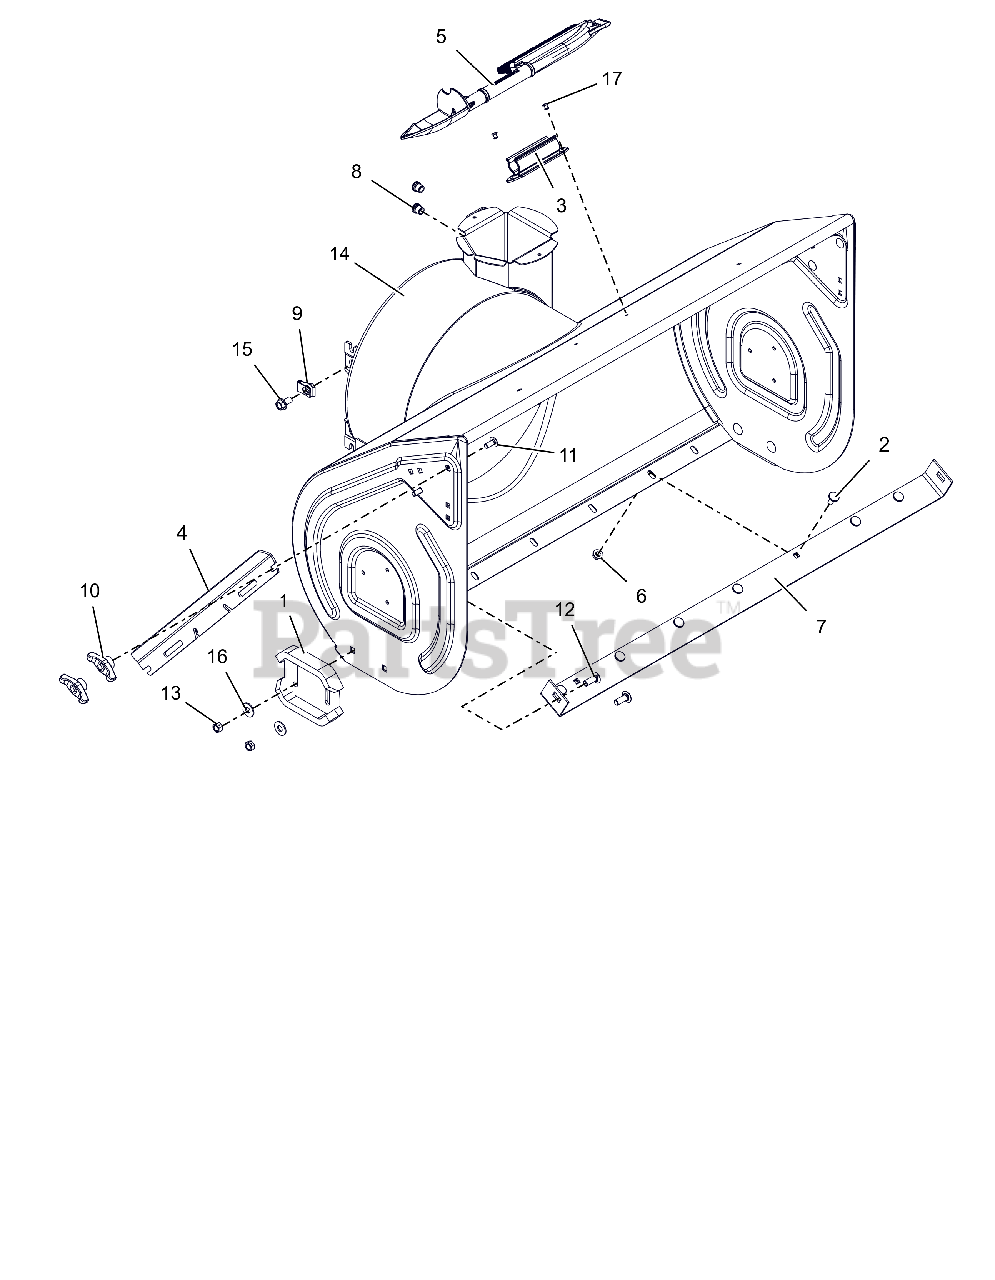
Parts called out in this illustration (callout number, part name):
1	RUNNER, SKID SHOE
2	BOLT, MODIFIED HEAD CARRIAGE
3	MOUNT, SNOW CLEAN OUT
4	CUTTER, DRIFT
5	DEVICE, SNOW CLEAN OUT W/BRUSH
6	@NUT-LK-TOP-FLG .31-18 YWZC
7	BLADE, SCRAPER-36"
8	NUT, THREADED INSERT .38-16
9	NUT-RTNR .375-16X.37
10	KNOB,WING .31-18 UNC NYL/TALC
11	@BLT-RHDSSQNK .31-18X.75 G5YZ
12	@BLT-RDHDSHSQNK.38-16X1.0 G5YZ
13	@NUT-LK-CTR .38-16 YWZC
14	BLOWER HOUSING W/DECAL 36"
15	BLT-SERHFWH .38-16X.75 YWZC
16	@WSHR-FL-STL.438X1.00X.083 YWZ
17	RVT-POP .187 YZ
